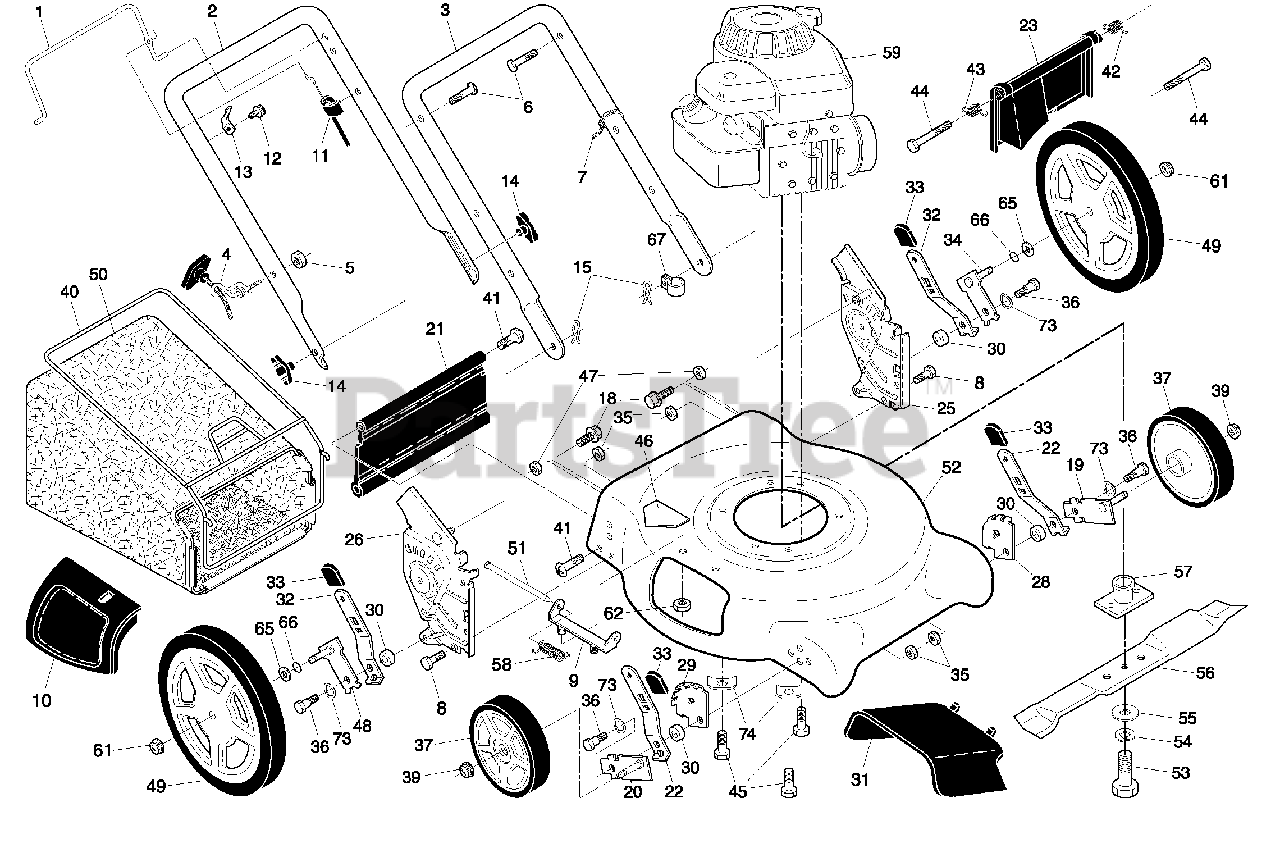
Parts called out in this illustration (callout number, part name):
1	Control Bar
2	Upper Handle
3	Lower Handle
4	Rope Guide
6	Handle Bolt
7	Wire Tie
8	Bolt
9	Hinge Bracket
10	Mulcher Door
11	Engine Zone Control Cable
12	Hex Washer Head Screw
13	Up-Stop Bracket
14	Handle Knob
15	Hairpin Cotter
18	Screw 1/4-20 x 3/8
19	Axle Arm Assembly, Front, LH
20	Axle Arm Assembly, Front, RH
21	Rear Skirt
22	Selector Spring, Front
23	Rear Door Assembly
25	Handle Bracket Assembly, LH
26	Handle Bracket Assembly, RH
28	Wheel Adjusting Bracket, Front, LH
29	Wheel Adjusting Bracket, Front, RH
30	Spacer
31	Discharge Deflector
32	Selector Spring, Rear
33	Selector Knob
34	Axle Arm Assembly, Rear, LH
35	Locknut, Hex 5/16-18
36	Shoulder Bolt 5/16-18
37	Wheel & Tire Assembly, Front, 7"
39	Locknut, Hex, Flanged
40	Frame, Grass Bag
41	Hinge Screw
42	Spring, Rear Door, LH
43	Spring, Rear Door, RH
44	Bolt, Rear Skirt
45	Hex Head Thread Rolling Screw 3/8-16 x 1
46	Danger Decal
47	Nut, Hex
48	Axle Arm Assembly, Rear, RH
49	Wheel & Tire Assembly, Rear, 12"
50	Grass Bag
51	Rod, Hinge
52	Housing Assembly
53	Hex Head Screw 3/8-24 x 1-3/8 Grade 8
54	Helical Lockwasher
55	Hardened Washer
56	21" Blade
57	Blade Adapter
58	Spring, Hinge
61	Locknut, Hex, Flanged
62	Locknut, Hex 1/4-20
65	Washer, Flat
66	O-Ring
67	Clip, Cable
73	Washer, Curved
74	Washer, Special, Engine
